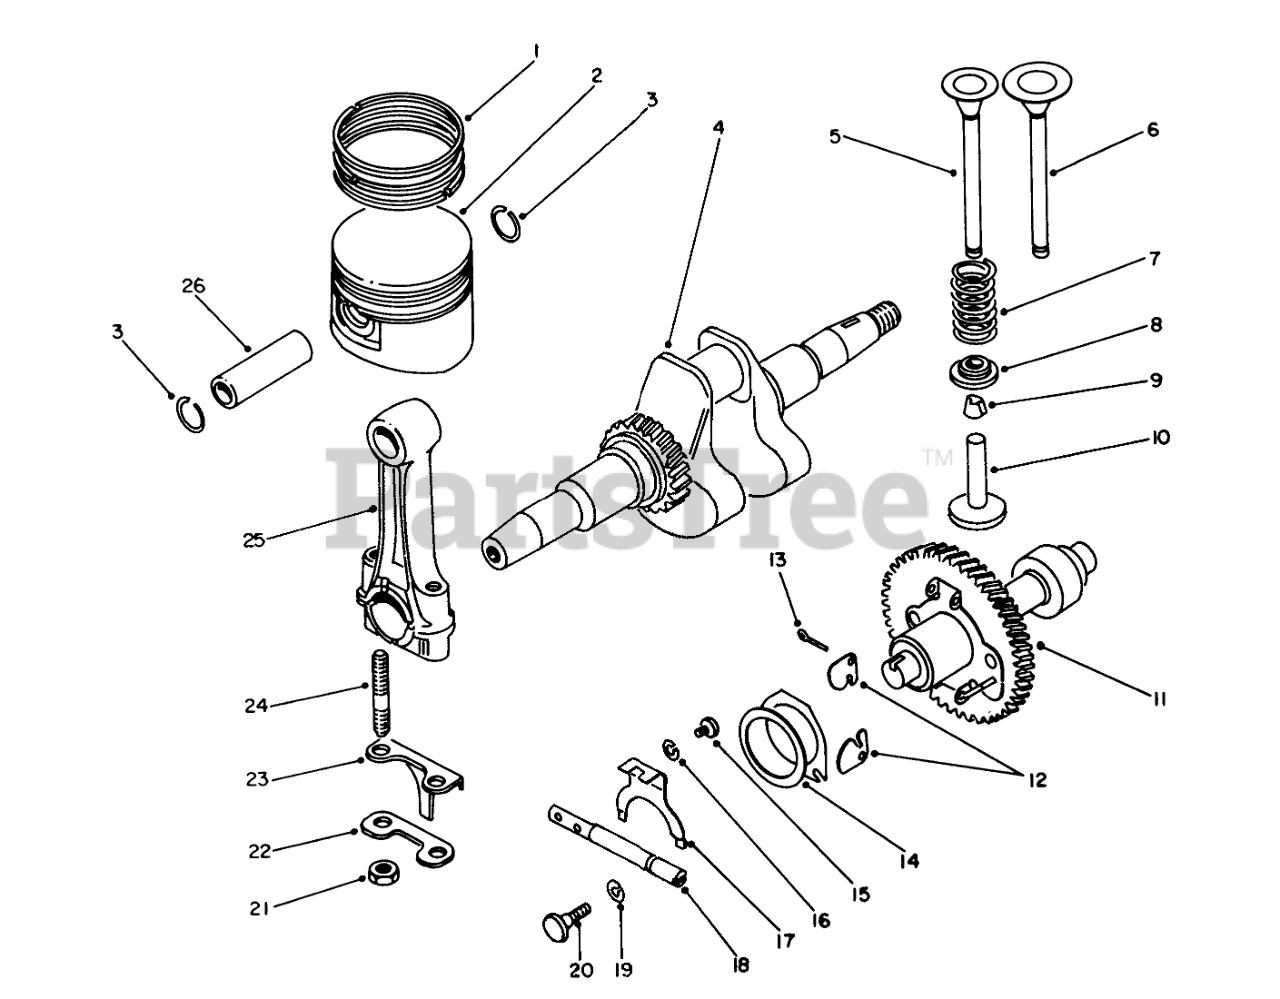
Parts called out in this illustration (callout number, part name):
1	RING SET
2	Piston
3	Circlip
4	Crankshaft
5	EXHAUST VALVE
6	Valve-Intake
7	Spring
8	Retainer
9	Cotter
10	Tappet
11	Camshaft
13	Cotter Pin
14	Spacer
15	Screw
16	Lockwasher
17	PLATE
18	Shaft
19	Gasket
20	Screw
22	LOCK PLATE
23	Plate-Splash
25	Connecting Rod (Incl. Ref. #21-24)
26	PISTON PIN
